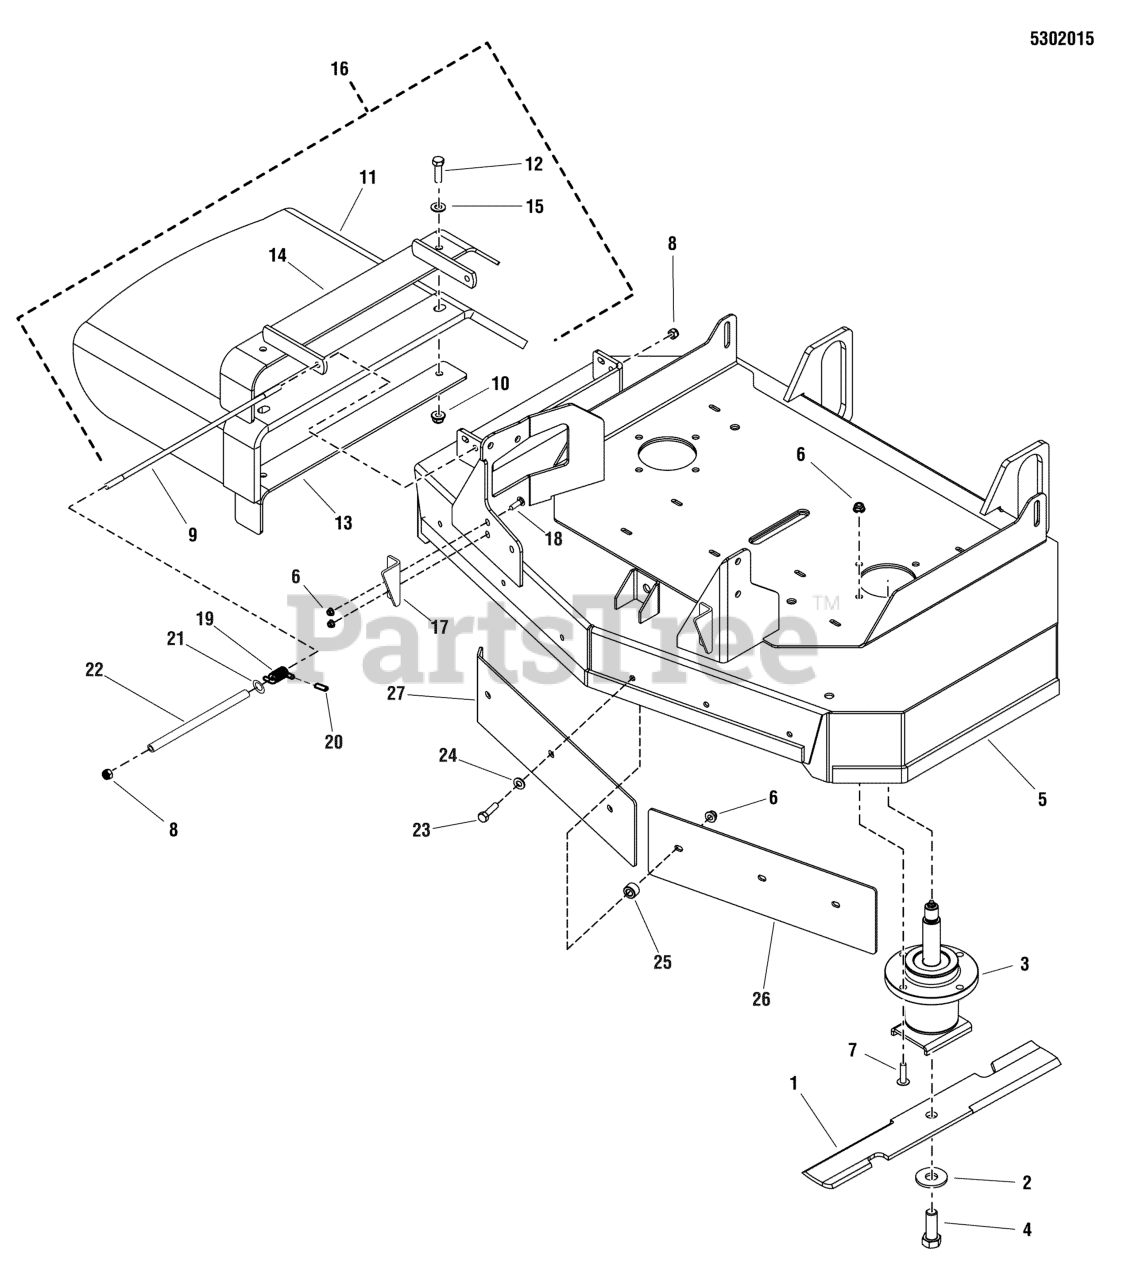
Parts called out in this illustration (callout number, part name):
1	BLADE, 18", SET OF THREE
2	WASHER, 5/8 USS
3	ASSM, SPINDLE, BLADE SADDLE
4	BOLT, 5/8-11 X 1-3/4 GD8
5	DECK SHELL W/ DECALS, EVS, 36 - RED
6	NUT, 5/16-18 HEX NYLOCK FLANGE
7	BOLT, 5/16-18 X 1 1/4 FLANGE
8	NUT, 5/16-24 HEX NYLON LOCK
9	ROD, 5/16 X 13.75, TBE
10	NUT, 3/8-16 HEX NYLOCK FLANGE
11	CHUTE, DISCHARGE, RUBBER
12	BOLT, 3/8-16 X 1-1/4" GD5 CZ
13	SUPPORT,DISCHARGE CHUTE - BLK
14	WELD, MOUNT, DISCHARGE CHUTE - BLK
15	WASHER, 3/8 SAE
16	KIT, DISCHARGE CHUTE, 44/48/52
17	PLATE, DECK STOP, EVO 48 - RED
18	BOLT, 5/16-18 X 1, CARRIAGE
19	SPRING, TORSION
20	CAP, PROTECTOR, .120 ID
21	WASHER, 5/16 FENDER
22	TUBE, 1/2 X 3/8 BLACK POLY, 8.25 LONG
23	BOLT, 5/16-18 X 1-1/4 GD5 YZ
24	WASHER, 5/16" SAE
25	SPACER, .39 X .75 X .50, CZ
26	PLATE, BLOCKOFF BAFFLE, LH, 36 - RED
27	PLATE, BLOCKOFF BAFFLE, RH, 36 - RED
